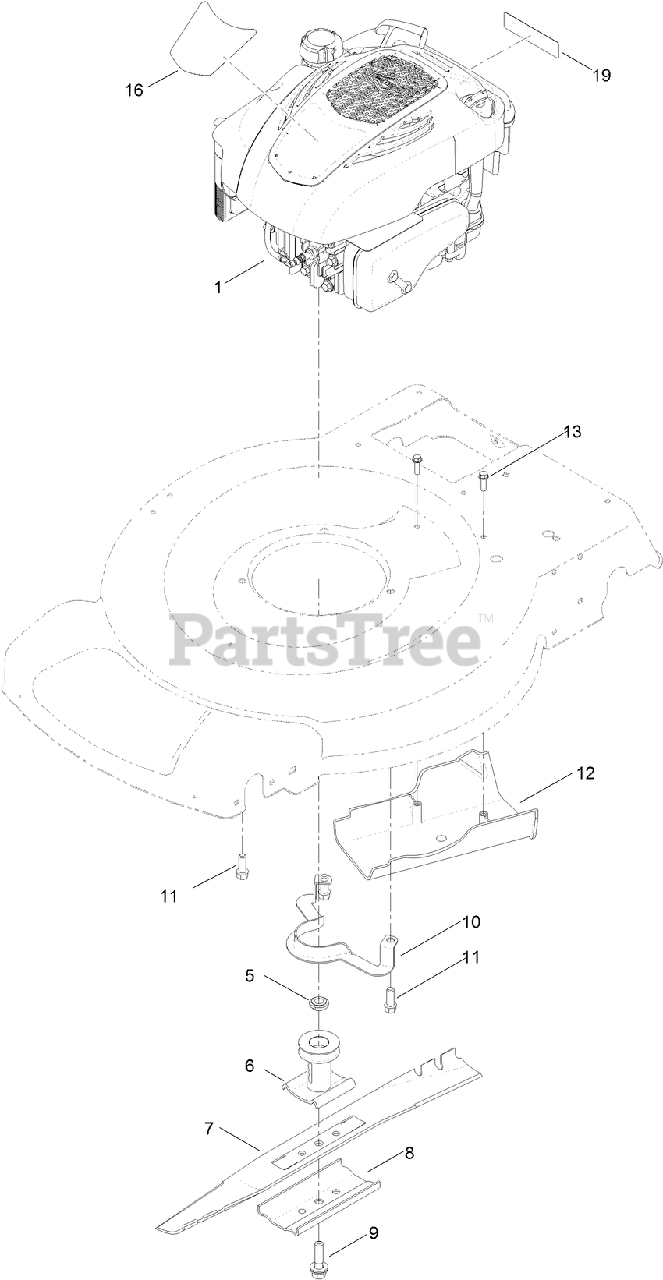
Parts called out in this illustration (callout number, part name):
5	SPACER-DRIVER
6	DRIVER-BLADE
8	SUPPORT-BLADE
9	BOLT-BLADE
10	GUIDE-BELT
11	SCREW-TAPTITE
12	COVER-BELT
13	SCREW-HWH
16	DECAL-SHROUD
19	DECAL-ARRESTER, SPARK
